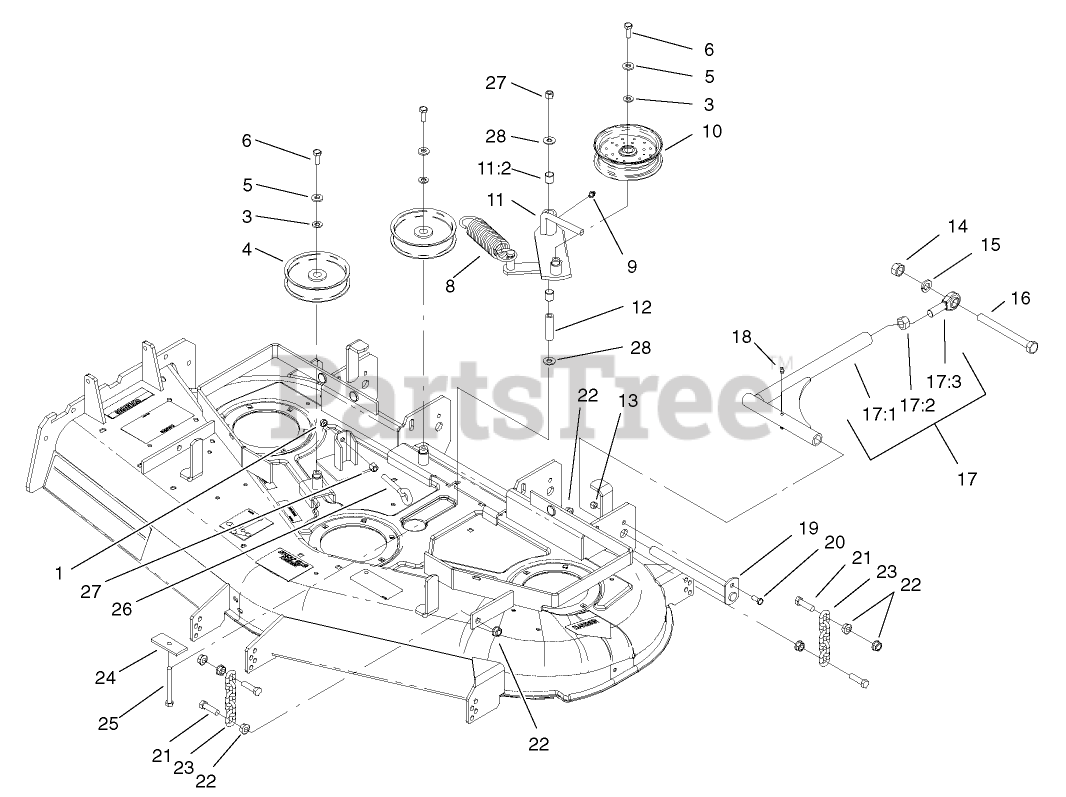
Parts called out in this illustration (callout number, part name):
1	NUT-HEX
3	WASHER-FLAT
4	PULLEY-IDLER
5	WASHER-BELLEVILLE
6	SCREW-HH
8	SPRING-EXTENSION
9	FITTING-GREASE, 90 DEG
10	PULLEY-IDLER
11	IDLER ARM ASM
11:2	SLEEVE-BEARING
12	BUSHING-PIVOT, IDLER
13	NUT-LOCK, NI
14	NUT-HEX
15	WASHER-LOCK
17	STRUT ASM
17:1	STRUT
17:2	NUT-HEX
17:3	BALLJOINT-SPHERICAL
18	FITTING-GREASE
19	PIN-STRUT
20	SCREW-HH
21	SCREW-CAP, HH
22	NUT-HF
23	CHAIN-LIFT, DECK
24	PLATE-RETAINER, BOLT
25	SCREW-HH
26	BOLT-EYE
27	NUT-LOCK, NI
28	WASHER-HARDENED
